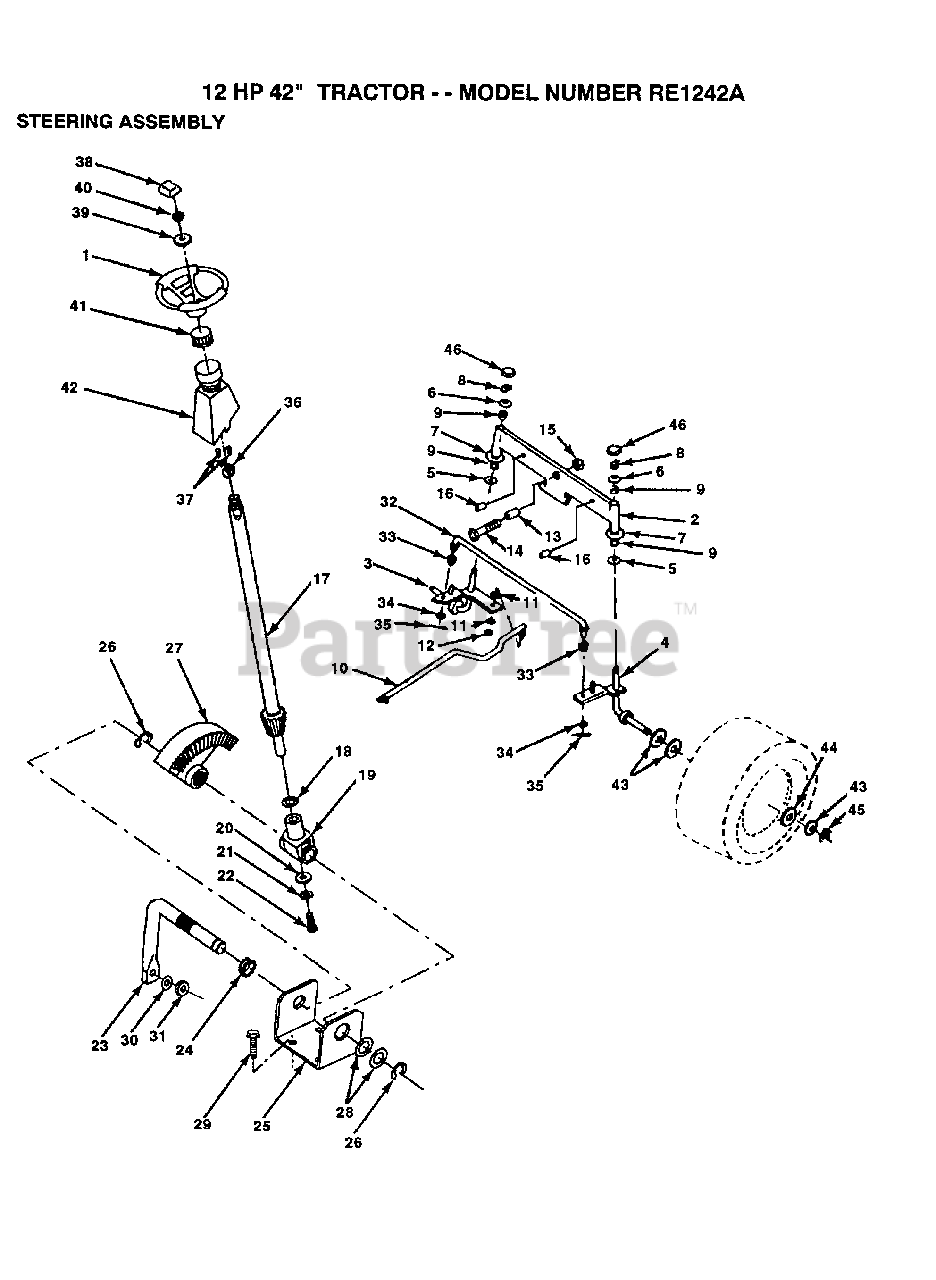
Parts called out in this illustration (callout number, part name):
3	SPINDLE LH
4	SPINDLE RH
5	WASHER .T
6	WASHER
7	WASHER
8	RING
9	COL. SRTG. BEAR.
11	LOCKWASHER
13	BEARING
14	BOLT HEX 5/8-11
16	AXLE PIN
17	SHAFT ASM
18	THRUST WASHER
19	SUPPORT.SHAFT
21	LOCKWASHER
22	"SCREW,SPECIAL"
24	NYLINER T
25	"BRKT,STEERING"
26	RING
28	WASHER .T
29	SCREW
30	LOCKWASHER
32	TIE ROD
33	BUSHING.DRAGLINK
34	WASHER
35	COTTER PIN
38	ST WHL INSERT CAP
39	WASHER T
40	GRIPCO NUT
41	ADAPTER-WHEEL LT
42	"TUBE, STR SHAFT"
43	WASHER
44	WASHER
45	RING
46	CAP
